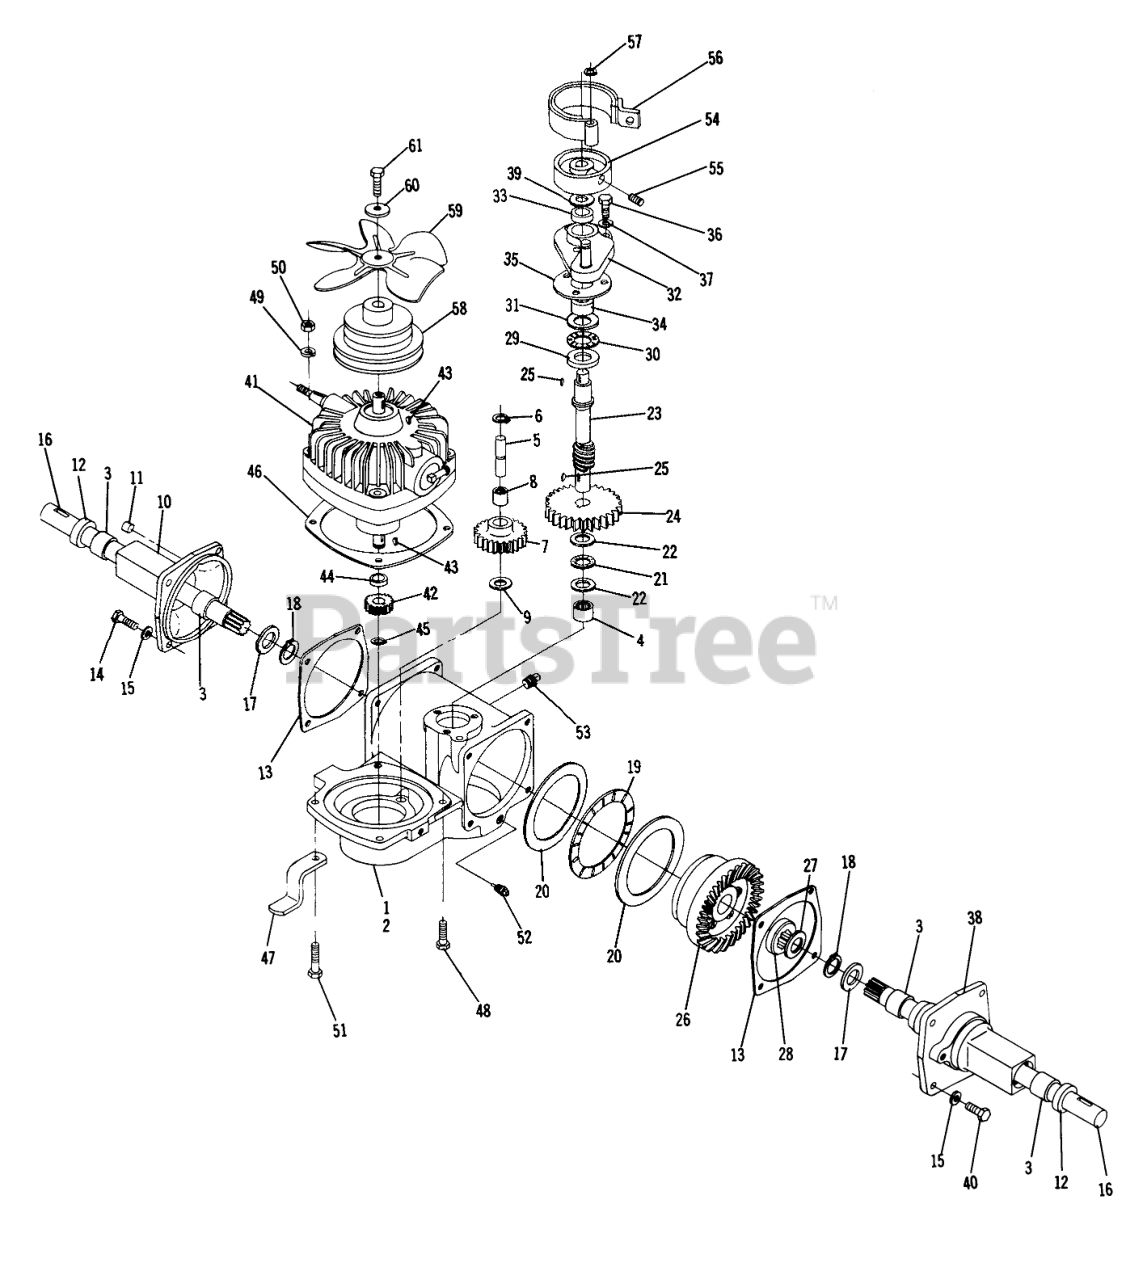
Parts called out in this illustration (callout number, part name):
1	Transmission Less Pump Brake Ass-y.
2	Housing
3	BEARING-NEEDLE
4	BEARING-NEEDLE
9	RACE THRUST
14	Bolt 3/8-16 x 1
15	Lockwasher
25	KEY WOODRUFF
26	BULLT 325
28	Bearing Axle
31	Rae-Thrust
36	Bolt 5/16-18 x
37	Lockwasher
38	Housing Axle L.H.
39	WASHER-THRUST
40	Bolt 3/8-16 x 1
41	Engine Speed Control
43	KEY WOODR 1/8X1/2 DI
47	Bracket-Stop
48	Bolt Hex 3/8-16 x 1
49	Washer
50	3/8-16 E.S.
51	Bolt 3/8-16 x 3 3/4"
52	Plug 1/4 Pipe
55	Screw 1/4-20 x 5/8
59	FAN
61	Bolt Hex 1/4-20 x 1 1/4 Nylok
